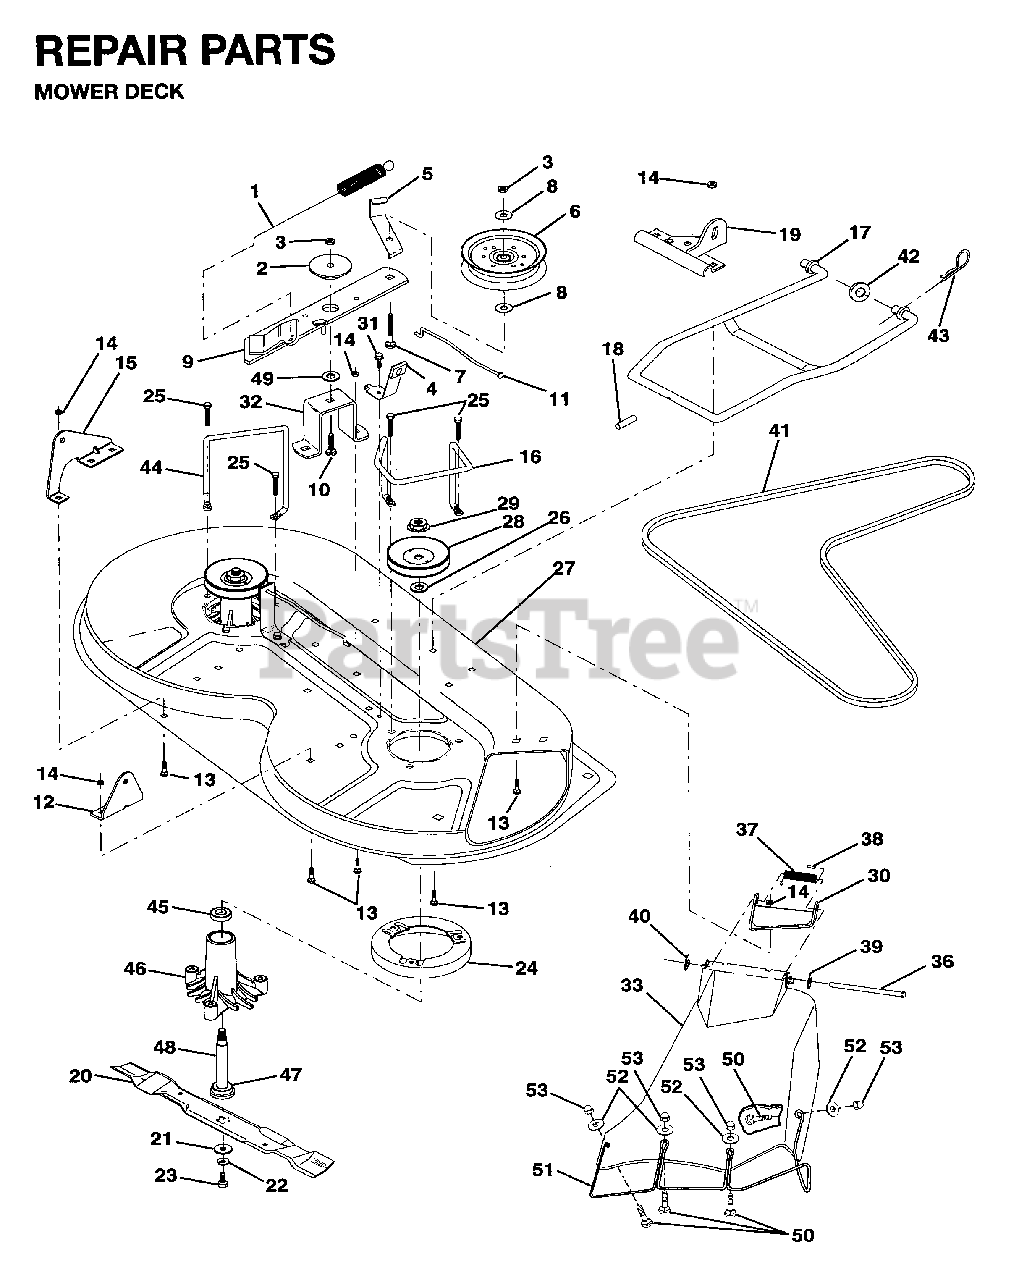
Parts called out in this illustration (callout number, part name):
1	SPRING-MOWER CLUTCH
2	SPACER RETAINER
3	LOCKNUT
4	BRAKE ASSEMBLY
5	IDLER BELT GUIDE
6	PULLEY.IDLER.FLAT
7	BOLT
8	WASHER
9	IDLER ARM ASSY
10	BOLT.3/8-14X1.25
11	BRAKE ROD
12	BRKT LIFT REAR
13	BOLT
14	NUT.71038.31-18.HEX.NYLOCK
15	BRKT LIFT REAR LH
16	KEEPER RH
17	MOWER LINK STABILIZER
18	PIN GROOVE
19	BRKT LINK STABILIIZER
20	BLADE, HI-LIFT 36" PREMIUM
21	WASHER.BLADE
22	WASHER, LOCK 3/8
23	BLADE BOLT
24	STRIPPER
25	SCREW
26	WASHER
27	MOWER HOUSING
28	PULLEY
29	NUT
30	BRACKET ASM DEFLECTOR
32	SUPT,IDLER ARM
33	DEFLECTOR
36	HINGE ROD
37	SPRING TORSION
38	CAP-SLEEVE LT
39	WASHER - 15X7.3X1.6
40	NUT PUSH M
42	WASHER - M12
43	SPRING RETAINER
44	KEEPER LH
46	HSG MANDREL
47	BEARING
48	SHAFT ASM VENT
49	HARDENED WASHER
